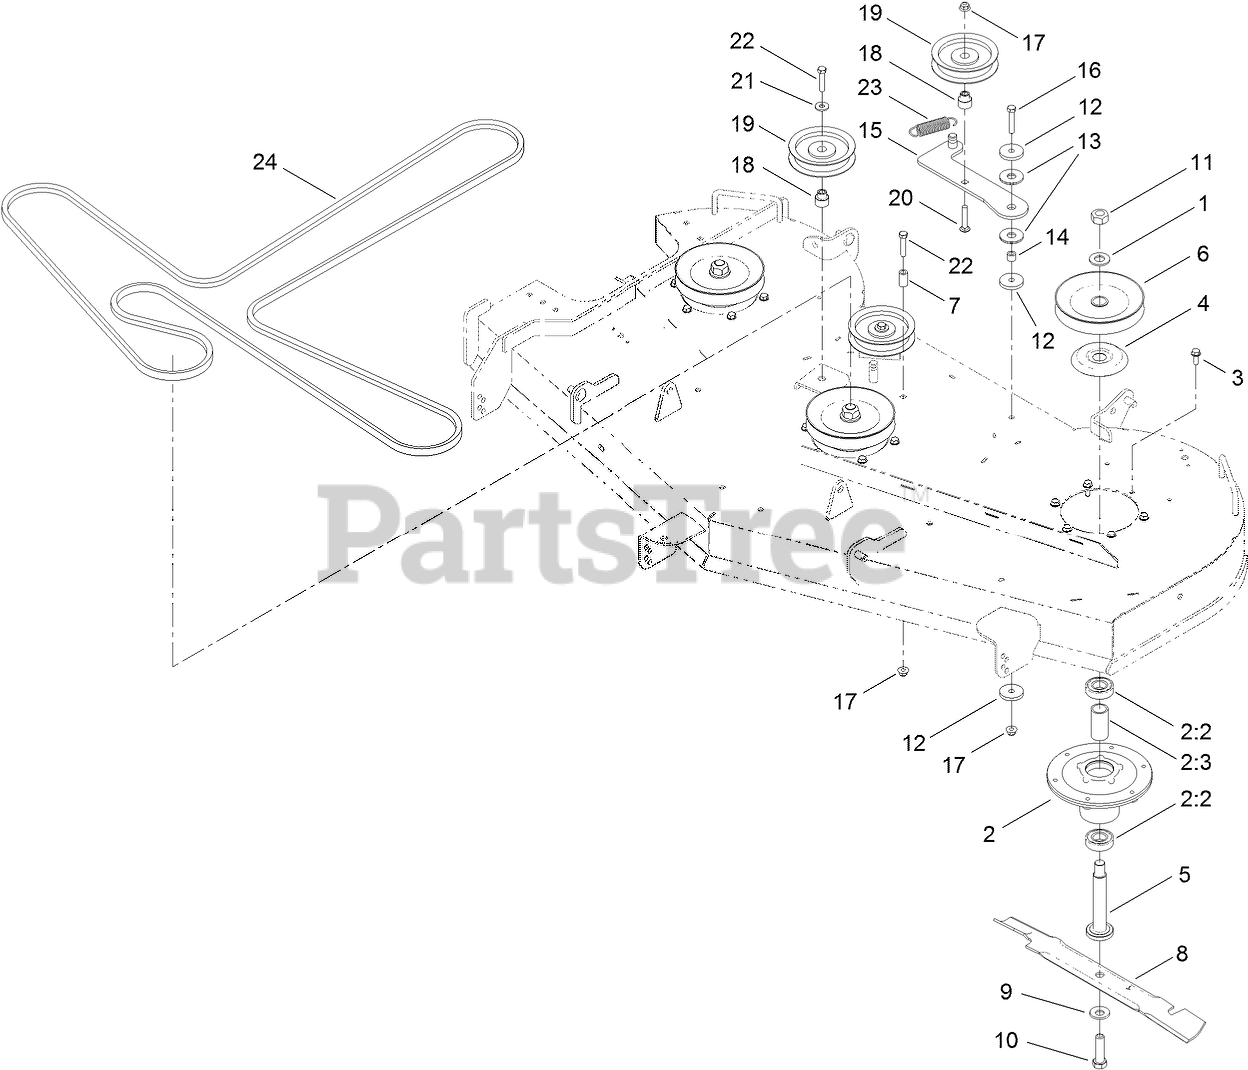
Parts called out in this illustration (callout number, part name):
1	WASHER
2	SPINDLE ASM
2:2	BEARING-BALL
2:3	SPACER-BEARING
3	SCREW-TAPTITE
4	SHIELD-BEARING
5	SHAFT-SPINDLE
6	PULLEY
7	SPACER
8	BLADE-HI FLOW, 20.5 INCH
9	WASHER-BELLEVILLE
10	SCREW-BLADE
11	NUT-HEX
12	WASHER-PLAIN
13	WASHER-FRICTION, COMPOSITE
14	BUSHING-LEVER, LIFT
15	ARM-IDLER
16	SCREW-HH
17	NUT-HF, NI
18	BUSHING-IDLER
19	PULLEY-IDLER
20	SCREW-CARR
21	WASHER-HARDENED
22	SCREW-HH
23	SPRING-EXTENSION
24	BELT-V
